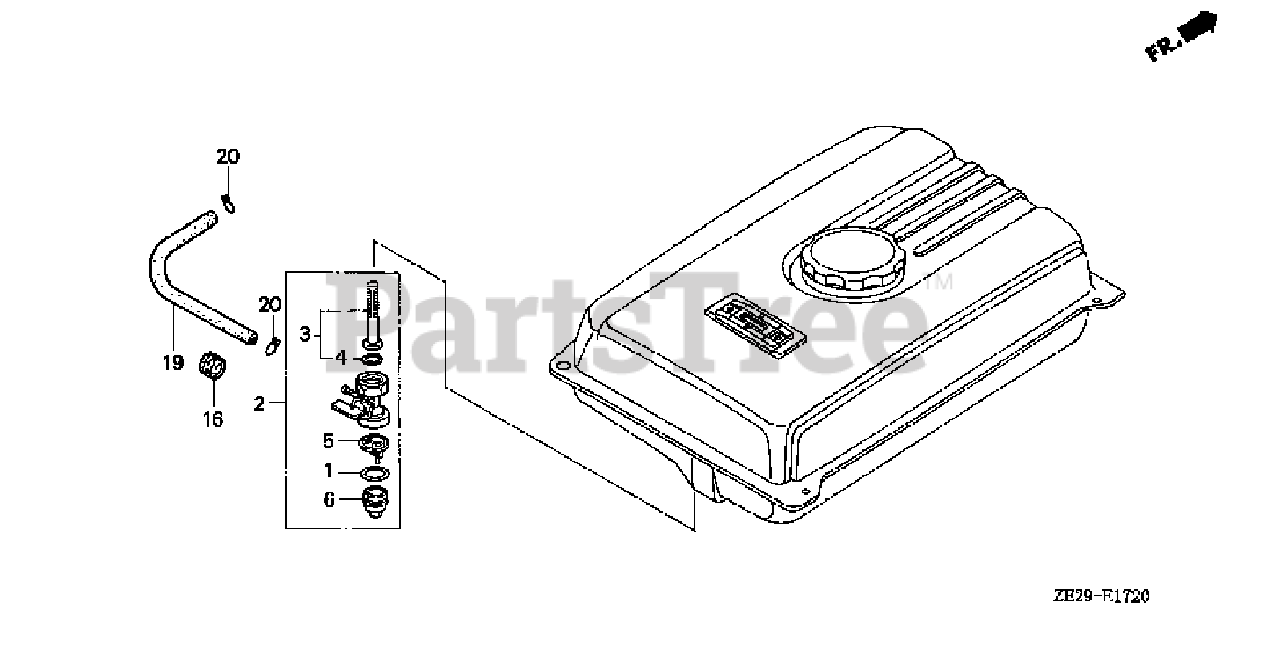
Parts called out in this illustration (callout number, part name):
1	GASKET, FUEL STRAINER CUP
2	PETCOCK ASSY.
3	SCREEN, FUEL STRAINER
4	O-RING (9X1.3)
5	FILTER, CUP
6	CUP, FUEL STRAINER
16	RUBBER, FUEL TUBE
19	BULK HOSE, FUEL (4.5X3000) (4.5X190)
20	CLIP, TUBE (B8)
